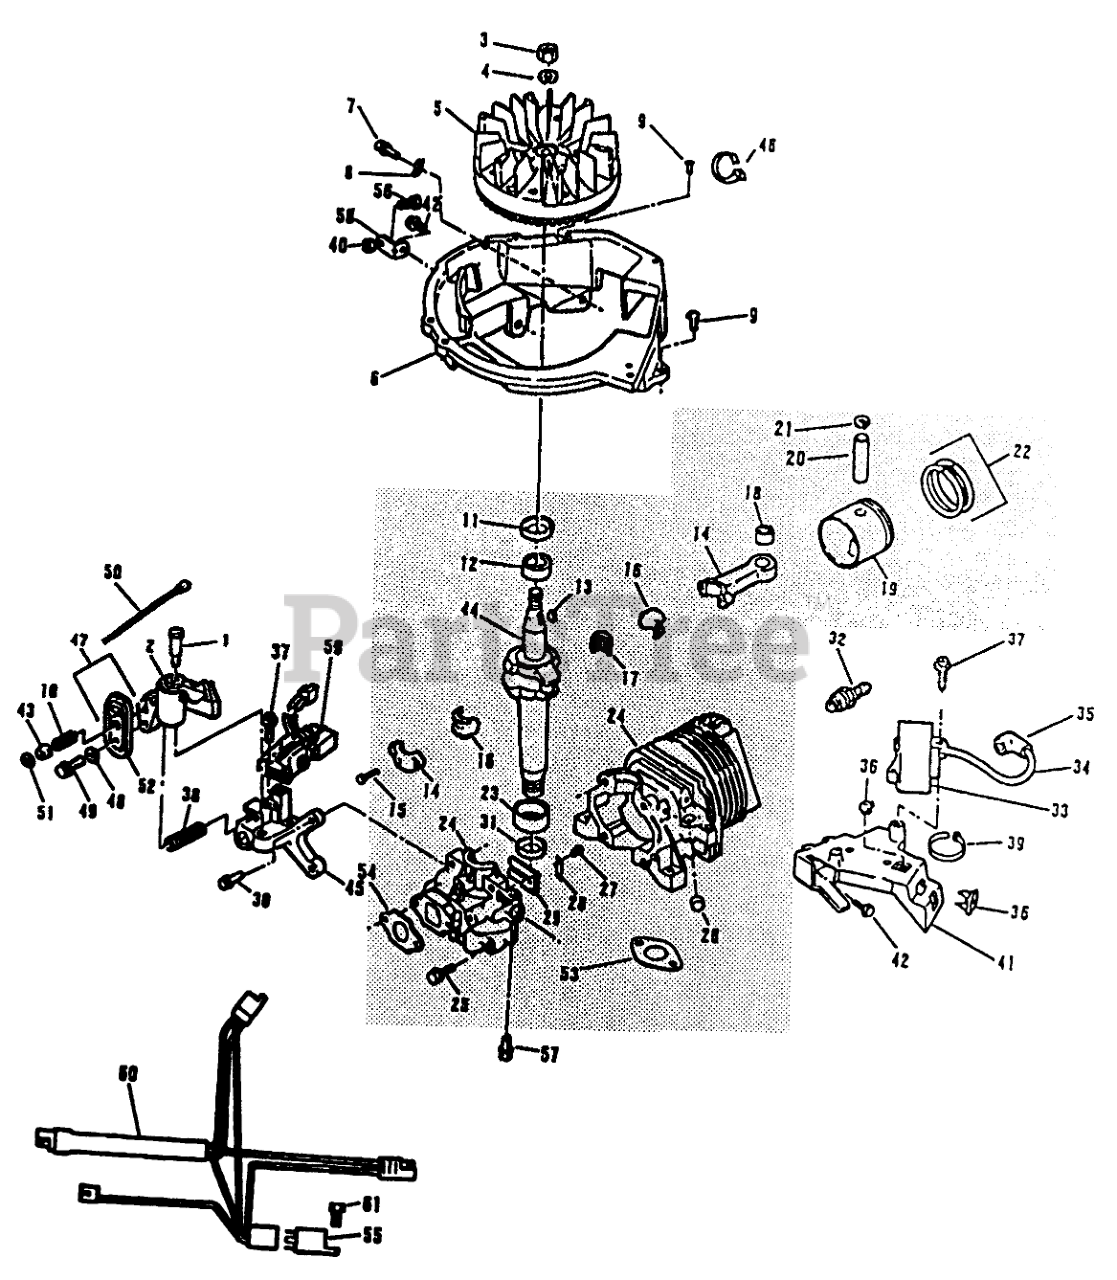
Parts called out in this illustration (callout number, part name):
1	SCREW-SHOULDER
2	BRAKE AY FE
3	NUT
4	WASHER-LOCK
5	FLYWHEEL ASSY F
6	BASE SHROUD F
7	SCREW F
8	"J" CLIP F
9	SCREW F
10	SPRING
11	SEAL-OIL
12	BEARING V
13	KEY
15	SCREW-HSH
16	LINER ASM
17	BEARING-NEEDLE
18	BEARING AY F
20	PIN-WRIST VF
21	RING-RETAINING
22	F-RING SET
23	BEARING V
24	CYL.C'CASE AY S
25	SCREW-H.W.HD. F
26	PLUG-CORE VF
27	SCREW-HH
28	PLATE-BACKUP, REED
29	REED-CARBURETOR
30	SCREW
31	SEAL-OIL
32	Spark Plug
33	Module-C.D. Ignition & Lead
34	HT LEAD&COVER XEV
36	NUT-CLIP
37	SCREW F
38	SPRING-BRAKE
39	TIE-CABLE
40	NUT-LOCK F
41	C.D. BRKT F
42	SCREW F
43	ACTUATOR-LEVER, BRAKE
44	Crankshaft
45	BRACKET F
46	STRAP-TIE
47	Switch Kit
48	WASHER
49	Screw
50	WIRE LEAD AY F
51	RETAINER S
52	Assembly-Case
53	Gasket
54	GASKET CARB S
55	RELAY E
56	BOLT F
57	Hex Socket Head Screw
58	BRACE, ALT F
59	ALTERNATOR AY F
60	Wire Harness Assembly
61	SCREW F
